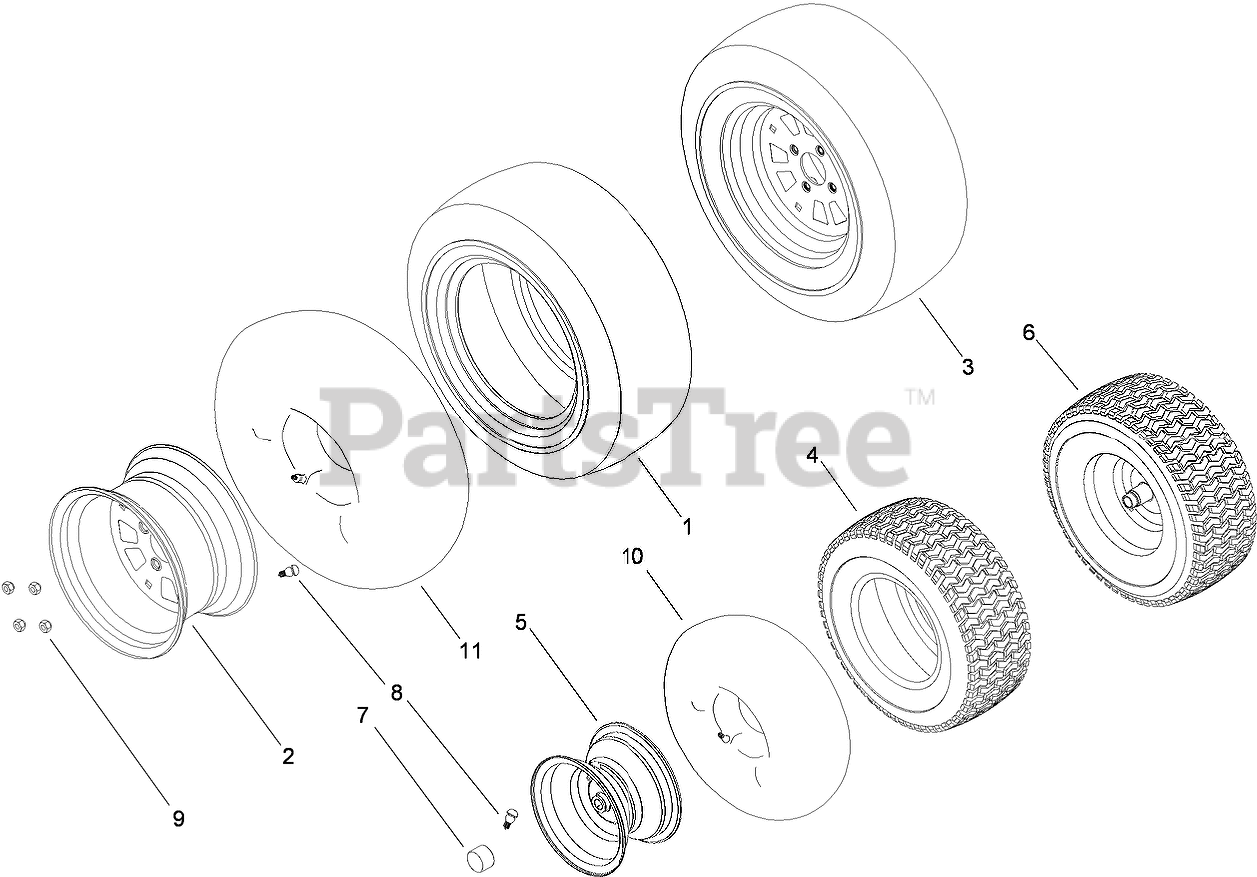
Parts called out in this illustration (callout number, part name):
1	TIRE-TURF
2	RIM ASM
3	WHEEL ASM
4	TIRE-TURF
5	RIM ASM
6	WHEEL ASM
7	CAP-HUB
8	VALVE-AIR, TUBELESS
9	NUT-LUG
10	TUBE-INNER
